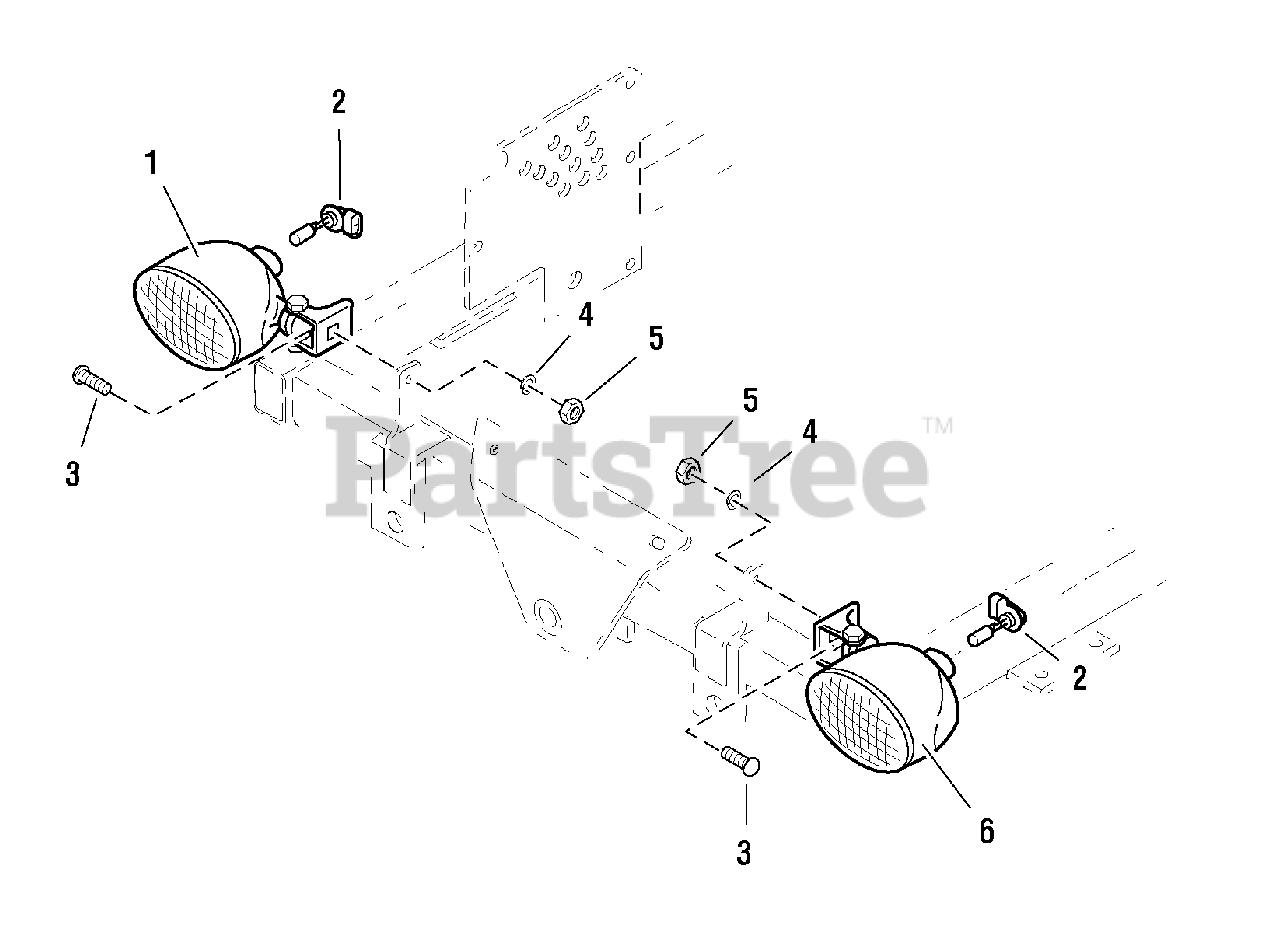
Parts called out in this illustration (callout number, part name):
1	HEADLIGHT-RH, Complete (includes Ref. 2-5)
2	BULB, Headlight
3	CARRIAGE BOLT, 5/16-18 x 1
4	WASHER, Lock, 5/16
5	NUT, Hex, 5/16-18
6	HEADLIGHT-LH, Complete (includes Ref. 2-5)
